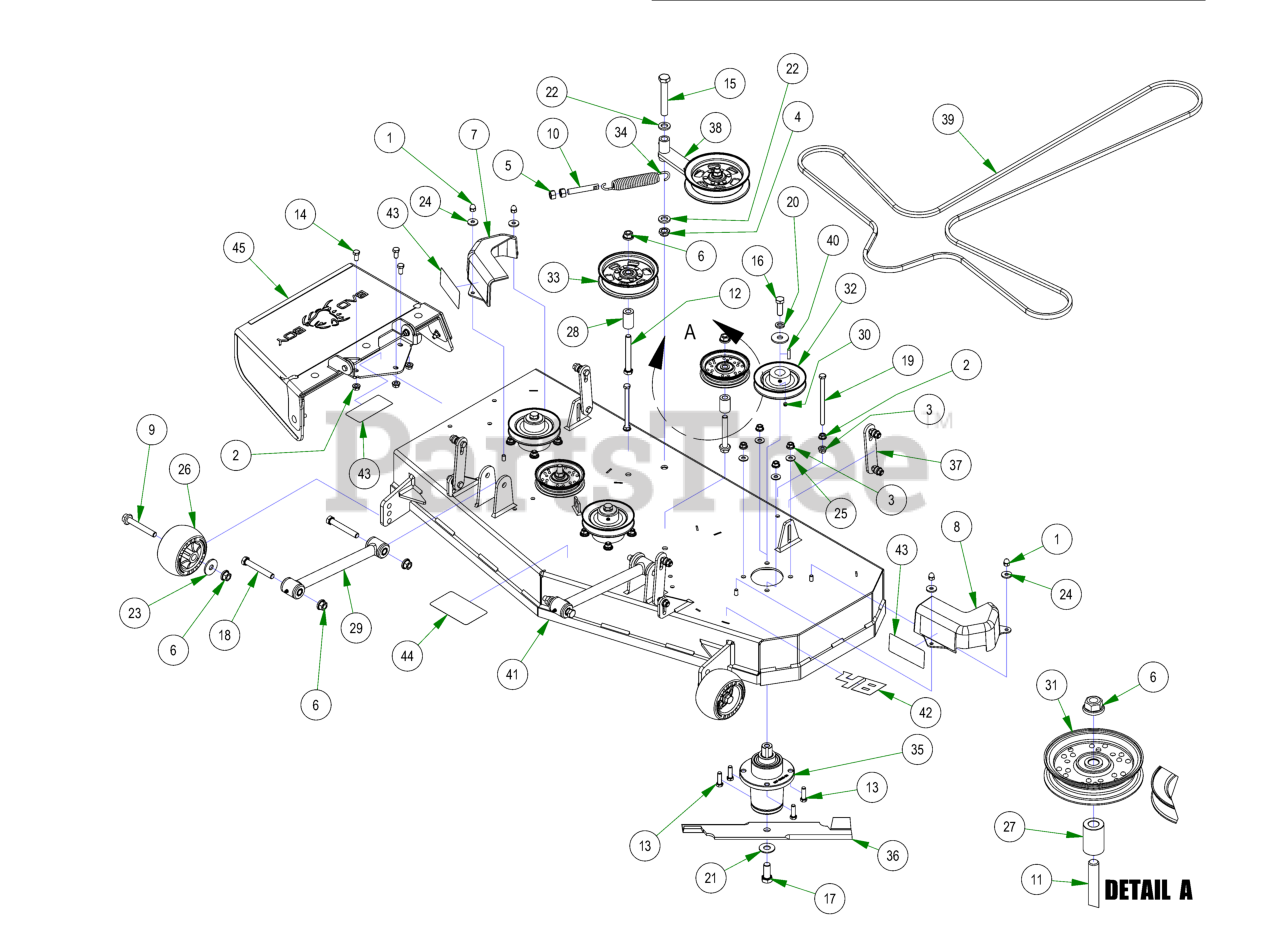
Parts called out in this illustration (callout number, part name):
1	5/16-18 ACORN NUT HIGH-CROWN ZC
2	3/8-16 HEX SERRATED FLANGE NUT HARD/ZINC
3	3/8-16 NYLON INSERT FLANGE LOCKNUT (GR.F) ZINC
4	5/8-11 NYLON INSERT JAM LOCKNUT ZINC
5	1/2-13 HEX NUT ZINC
6	1/2-13 NYLON INSERT FLANGE LOCKNUT ZINC
7	pulley cover chute side
8	pulley cover non-chute side
9	1/2-13 X 90MM HEX FLANGE BOLT W/SHOULDER (GR.8) ZINC
10	All Thread
11	1/2-13 X 3-1/2 HEX FLANGE BOLT (GR.8) ZINC
12	1/2-13 X 4 HEX CAP SCREW (GR.8) ZINC YELLOW
13	3/8-16 X 1-1/4 HEX CAP SCREW (GR.5) ZINC
14	3/8-16 X 3/4 HEX CAP SCREW (GR.5) ZINC
15	5/8-11 X 4 HEX CAP SCREW (GR.8) ZINC YELLOW
16	1/2-20 X 1-1/2 HEX CAP SCREW (GR.5) ZINC
17	5/8-18 X 1-1/2 HEX CAP SCREW (GR.8) ZINC YELLOW
18	1/2-13 X 3-1/2 HEX CAP SCREW (GR.5) ZINC
19	3/8-16 X 5-1/2 HEX CAP SCREW (GR.5) ZINC
20	1/2 SPLIT LOCKWASHER (GR.8) ZINC/YELLOW
21	5/8 USS FLAT WASHER (1-3/4" OD) GR.8 ZINC YELLOW
22	.635 ID X 1.120 OD X .140 THICK FLAT WASHER NYLON
23	1/2 BELLEVILLE WASHER (1-5/8 OD X .140 THK) ZINC
24	.360 ID X .983 OD X .120 THICK FLAT WASHER NYLON BLACK
25	5/16 USS FLAT WASHER (7/8 OD) ZINC
26	Deck Wheel
27	.502 ID X .750 OD X 1.500 Long Spacer
28	1 3/4" Pulley Spacer
29	Hybrid Turnbuckle/Deck Locator
30	5/16-24 X 1/4 SOCKET SET SCREW (CUP PT) PLAIN
31	4 3/4 Idler Pulley - ABFI-76
32	5" Spindle Deck Pulley
33	5-3/4 Idler Pulley
34	Deck Idler Spring
35	Spindle Assembly
36	48" ZT/Mav/Compact Outlaw Blade with Fusion
37	Deck Hanger Assembly
38	2017 MZ/ZT Deck Idler Assembly
39	B147 Deck Belt
40	1/4 X 1 SQ MACHINERY KEY 1018 STL PLN
41	2023 48" x 5" Deck
42	48" Deck Decal
43	Danger Decal-Spindle/Discharge
44	Deck Belt Route Decal
45	ZT Chute Assembly
